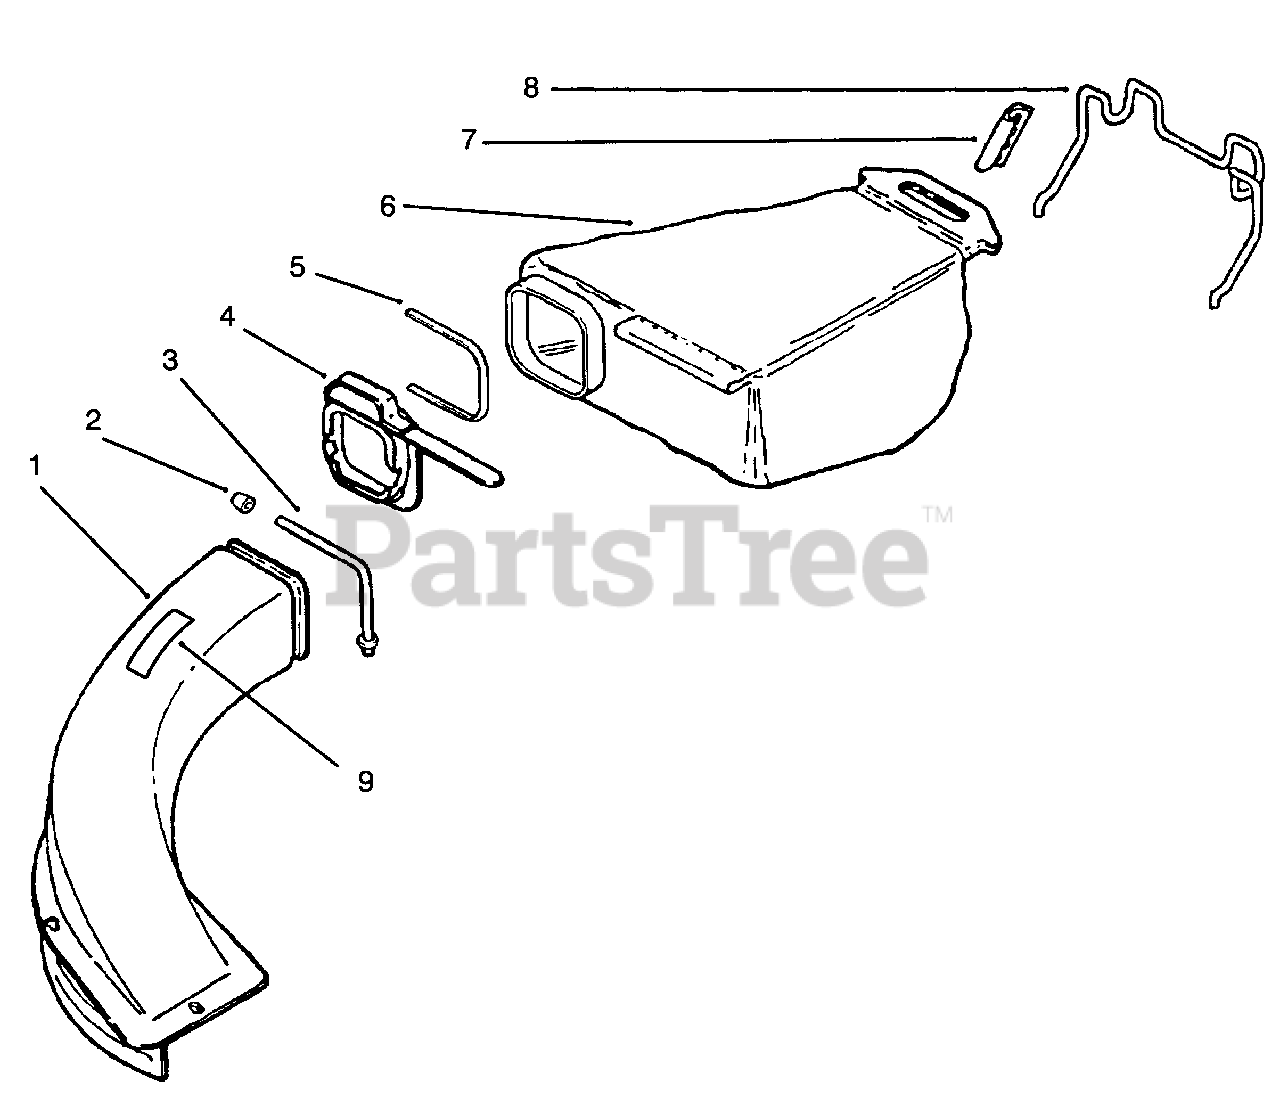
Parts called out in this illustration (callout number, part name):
1	Chute & Support Assembly (Incl. Ref. # 2,3 & 9)
2	Nut-Cap
3	Chute Support
4	Adaptor Assembly
5	Tie Strap
6	Bag Assembly
7	Hanger Clamp
8	Wide Hanger
9	Decal-Danger
